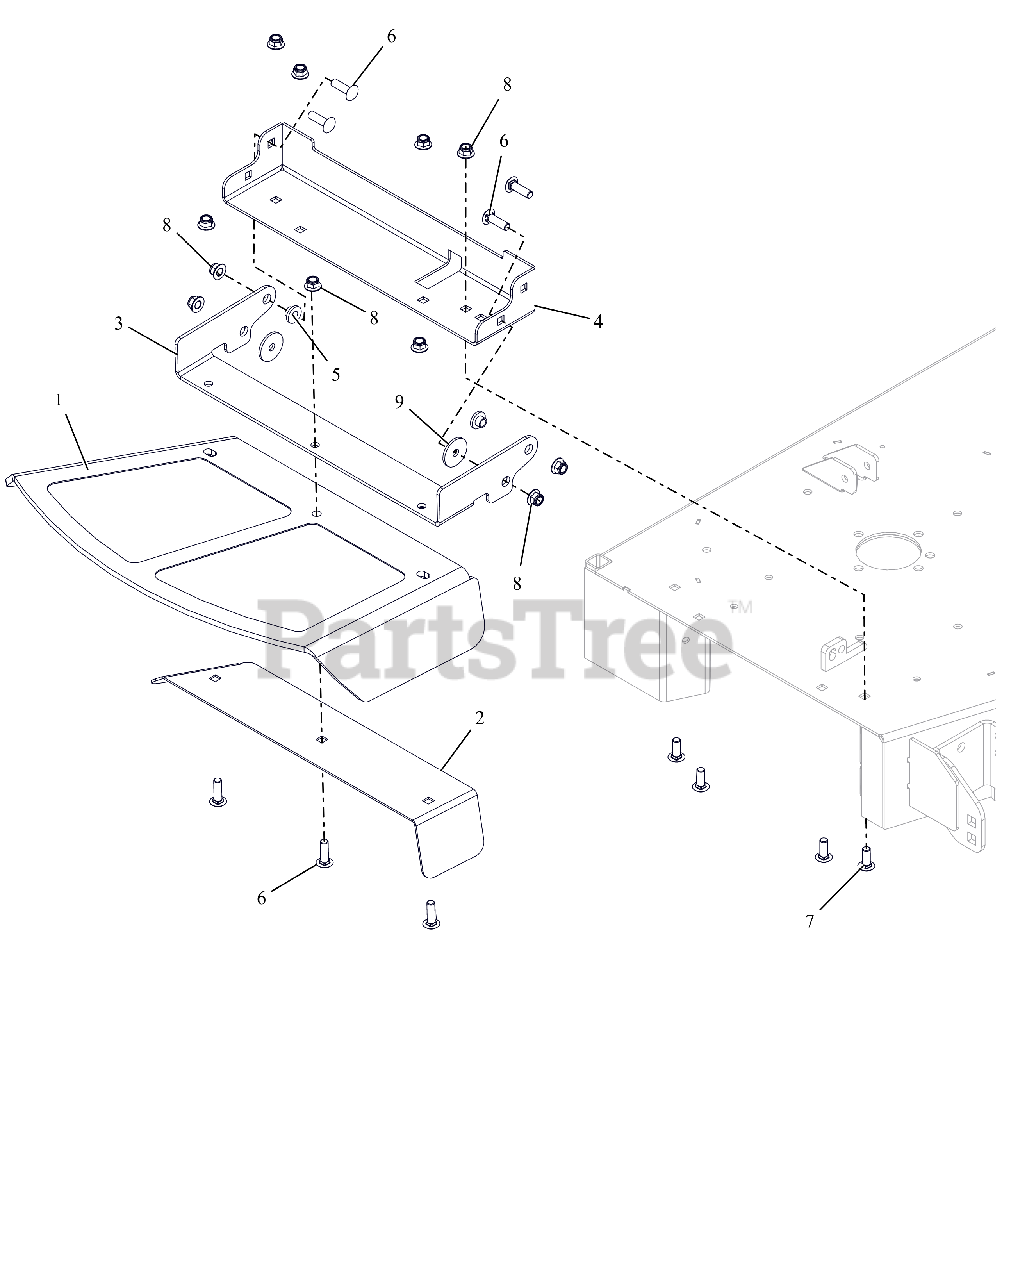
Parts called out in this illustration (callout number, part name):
1	CHUTE,48-60" FRMD RUBBER DISCH
2	PLT, DISCH. CHUTE CLMP-CE
3	BRKT, CE CHUTE MTG
4	WMT, DISCH. CHUTE-CE-W/SAFETY
5	BSHG-FLG .385X.500X.875X.406
6	@BLT-RHDSSQNK .38-16X1.25 G5YZ
7	@BLT-RDHDSHSQNK.38-16X1.0 G5YZ
8	@NUT-LK-NYL-FLG .38-16 YWZC
9	WSHR-FL-STL .380X1.50X.125YWZC
